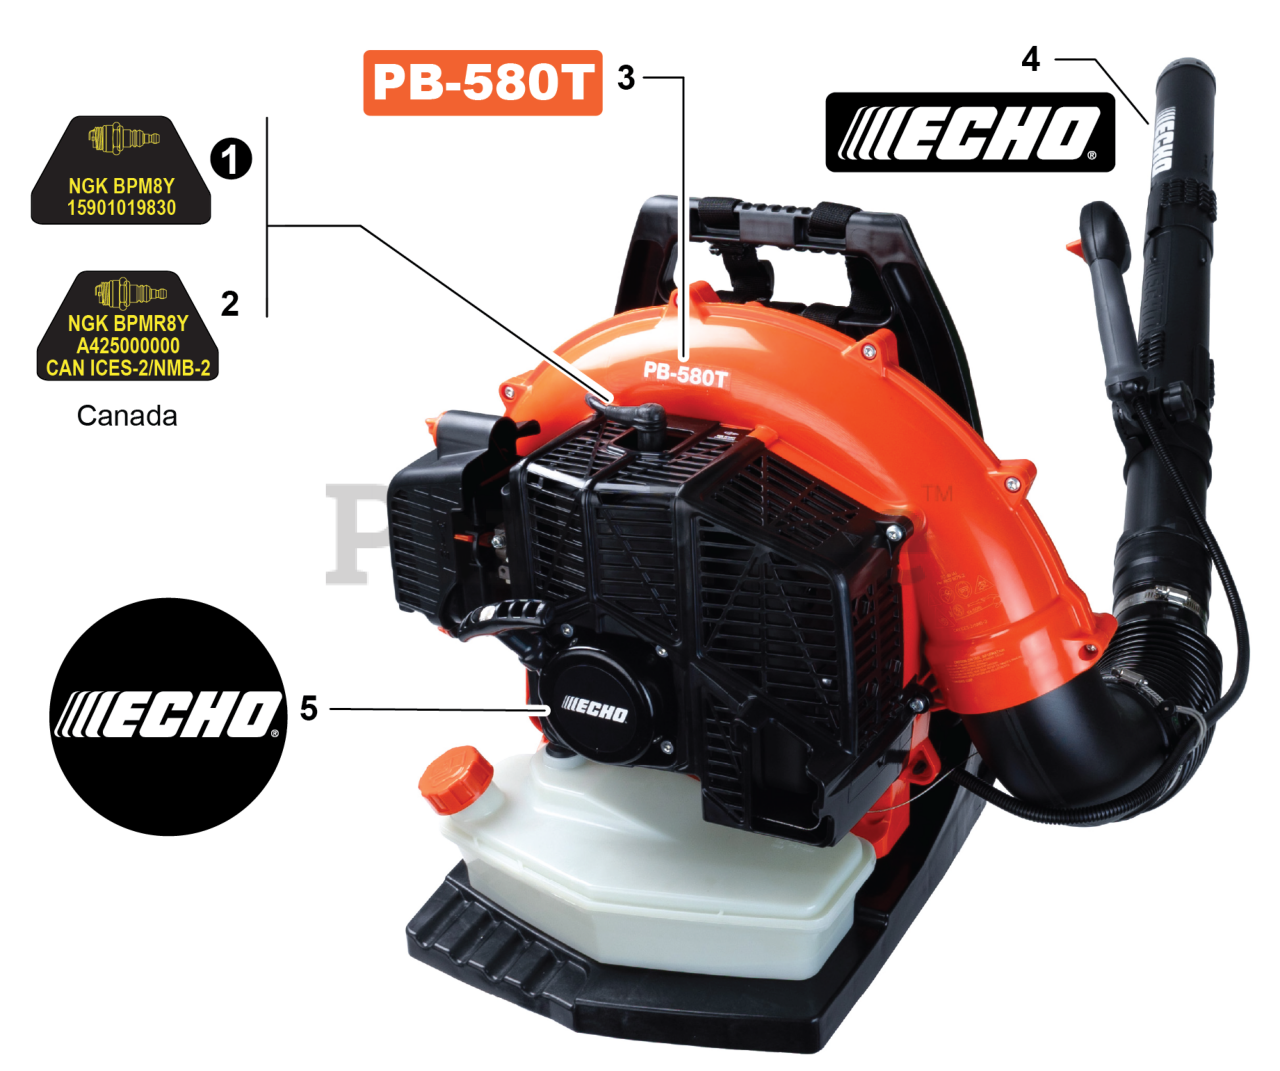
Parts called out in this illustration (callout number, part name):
1	LABEL - SPARK PLUG - BPM8Y
2	LABEL - SPARK PLUG - BPMR8Y
3	LABEL - MODEL - PB-580T
4	LABEL - ECHO
5	LABEL - STARTER - ECHO
